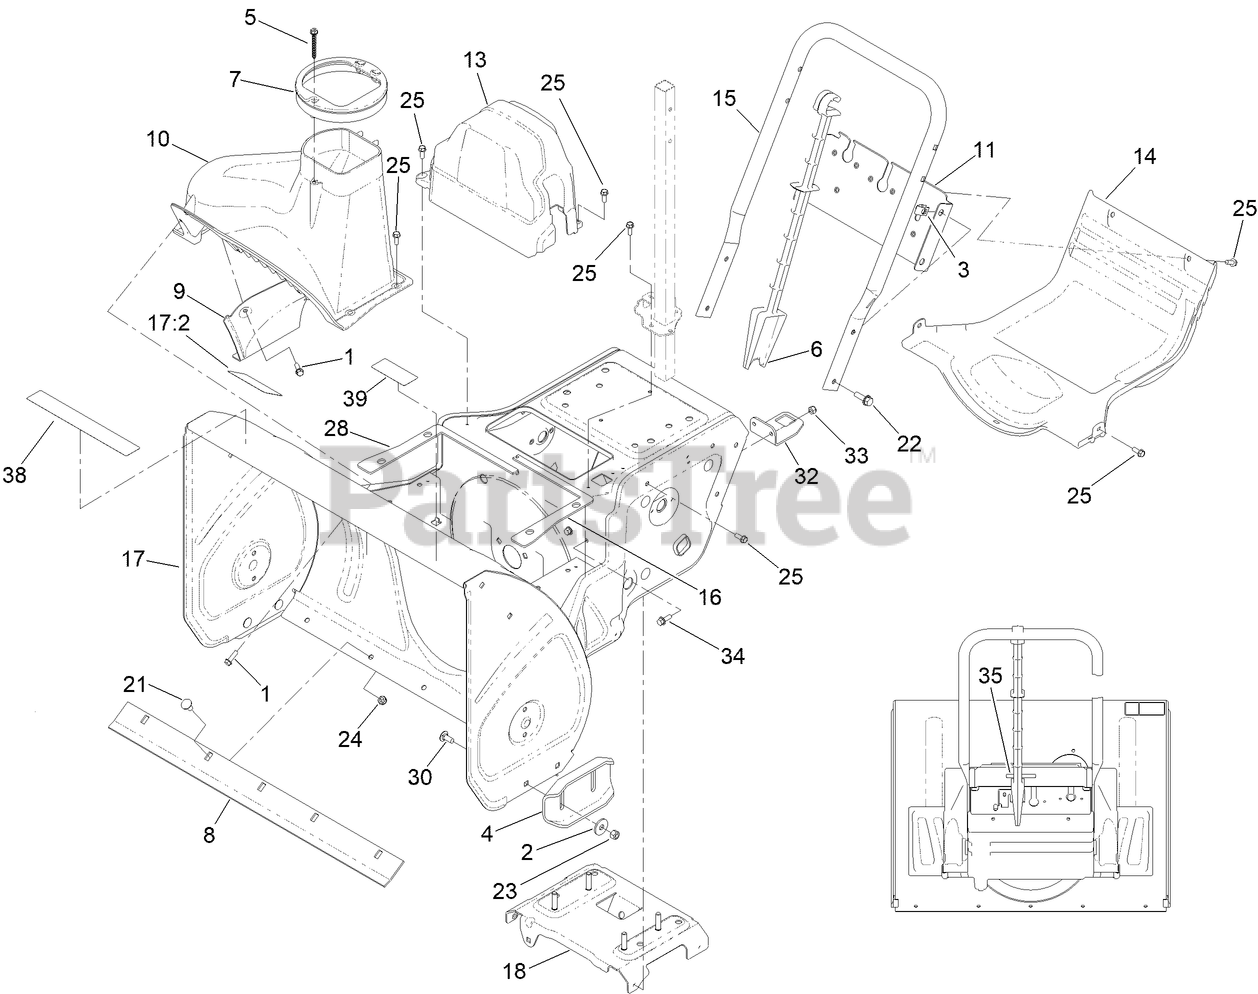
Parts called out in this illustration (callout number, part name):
1	SCREW-HWH
2	WASHER
3	NUT-U
5	SCREW-HWH, PLASTITE
6	STICK-CLEANOUT
7	GUIDE-CHUTE
8	SCRAPER-24 INCH
9	COVER-LINER
11	BRACE-FRAME
13	COVER-BELT
14	COVER-LOWER
15	HANDLE-LOWER, CTS
16	SEAL-HOUSING, LH
17	FRAME (ASM COMPACT 2 STAGE 24IN W/DECAL)
17:2	DECAL-DANGER, AUGER
18	BRACE-FRAME
21	SCREW-CARR
22	SCREW-HHF
23	NUT-LOCK, NI
24	NUT-LOCK, NI
25	SCREW-HWH
28	SEAL-HOUSING, RH
30	SCREW-CARR
32	BRACKET-POST, CHUTE
33	SCREW-HHF
34	NUT-HEX
35	DECAL-WARNING
38	DECAL - HARDENED GEARS
39	DECAL - COMPACT 24
